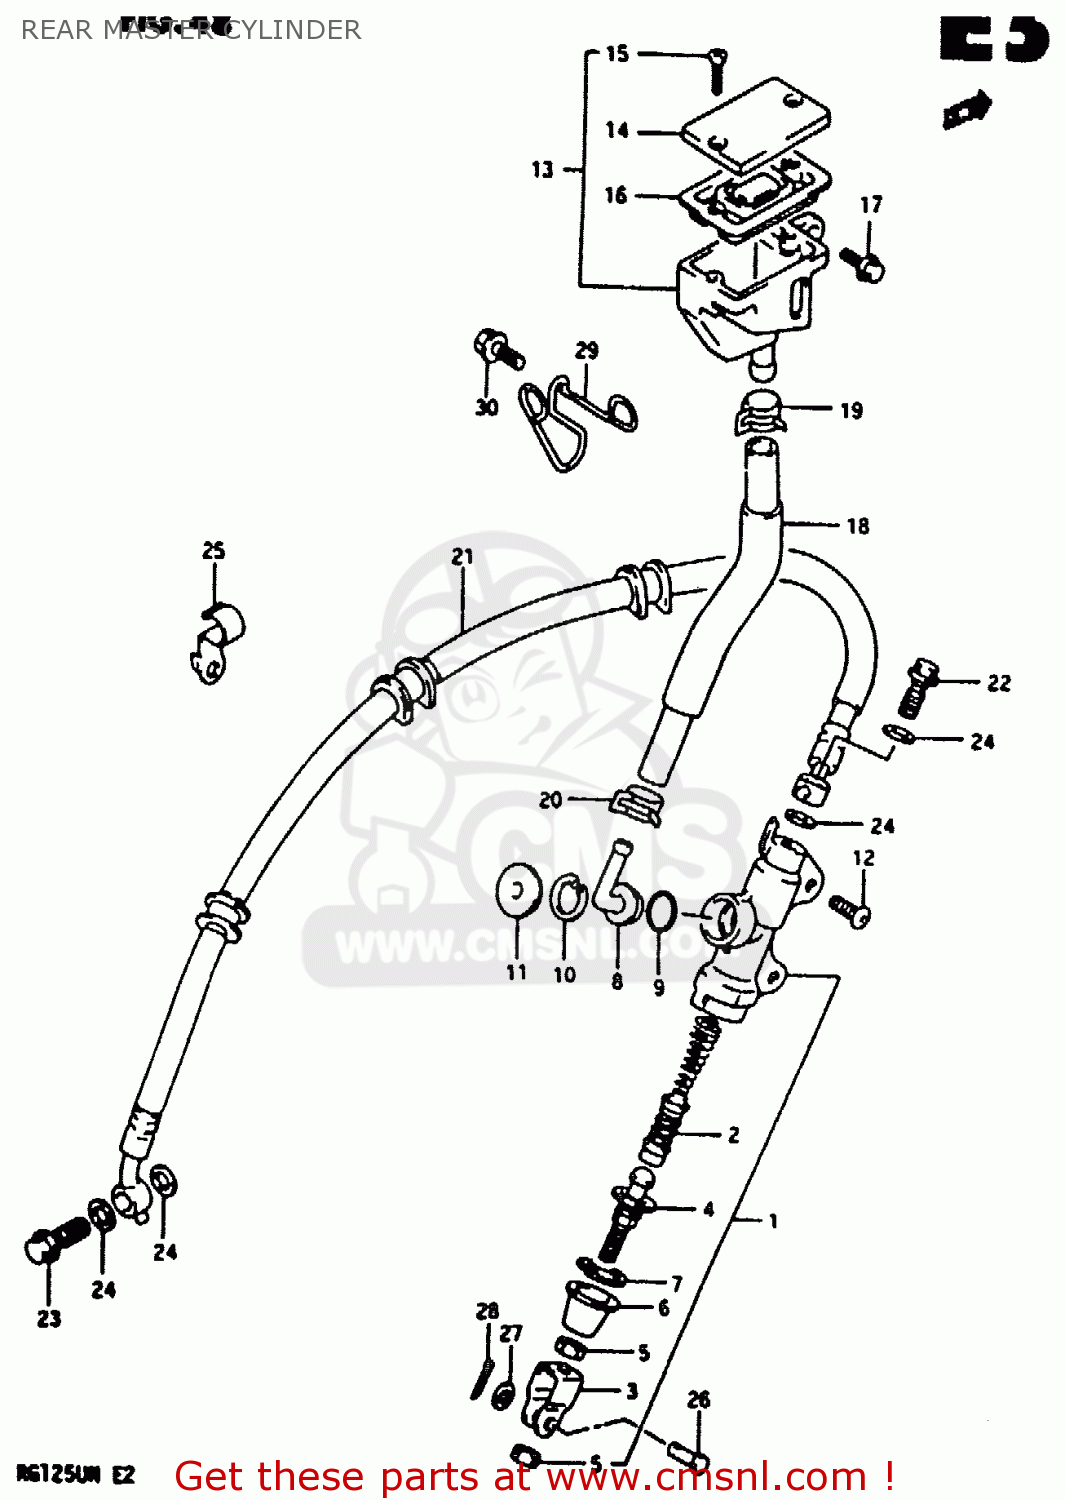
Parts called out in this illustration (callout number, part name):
1	CYLINDER ASSY, REAR MASTER
2	PISTON/CUP SET
3	YOKE
4	ROD,PUSH
5	NUT
6	BOOT
7	CIRCLIP
8	CONNECTOR
9	O RING
10	CIRCLIP
11	COVER,DUST
12	BOLT(8X20)
13	TANK ASSY,RR RESERVOIR
14	CAP
15	SCREW
16	DIAPHRAGM
17	BOLT
18	HOSE,RESERVOIR TANK
19	CLIP
20	CLAMP
21	HOSE, REAR BRAKE
22	BOLT 10X1.25X24
23	BOLT UNION
24	WASHER(10X15X1.5)
25	CLAMP, REAR BRAKE HOSE
26	PIN
27	WASHER
28	PIN
29	GUIDE, RESERVOIR TANK HOSE
30	BOLT 6X16
